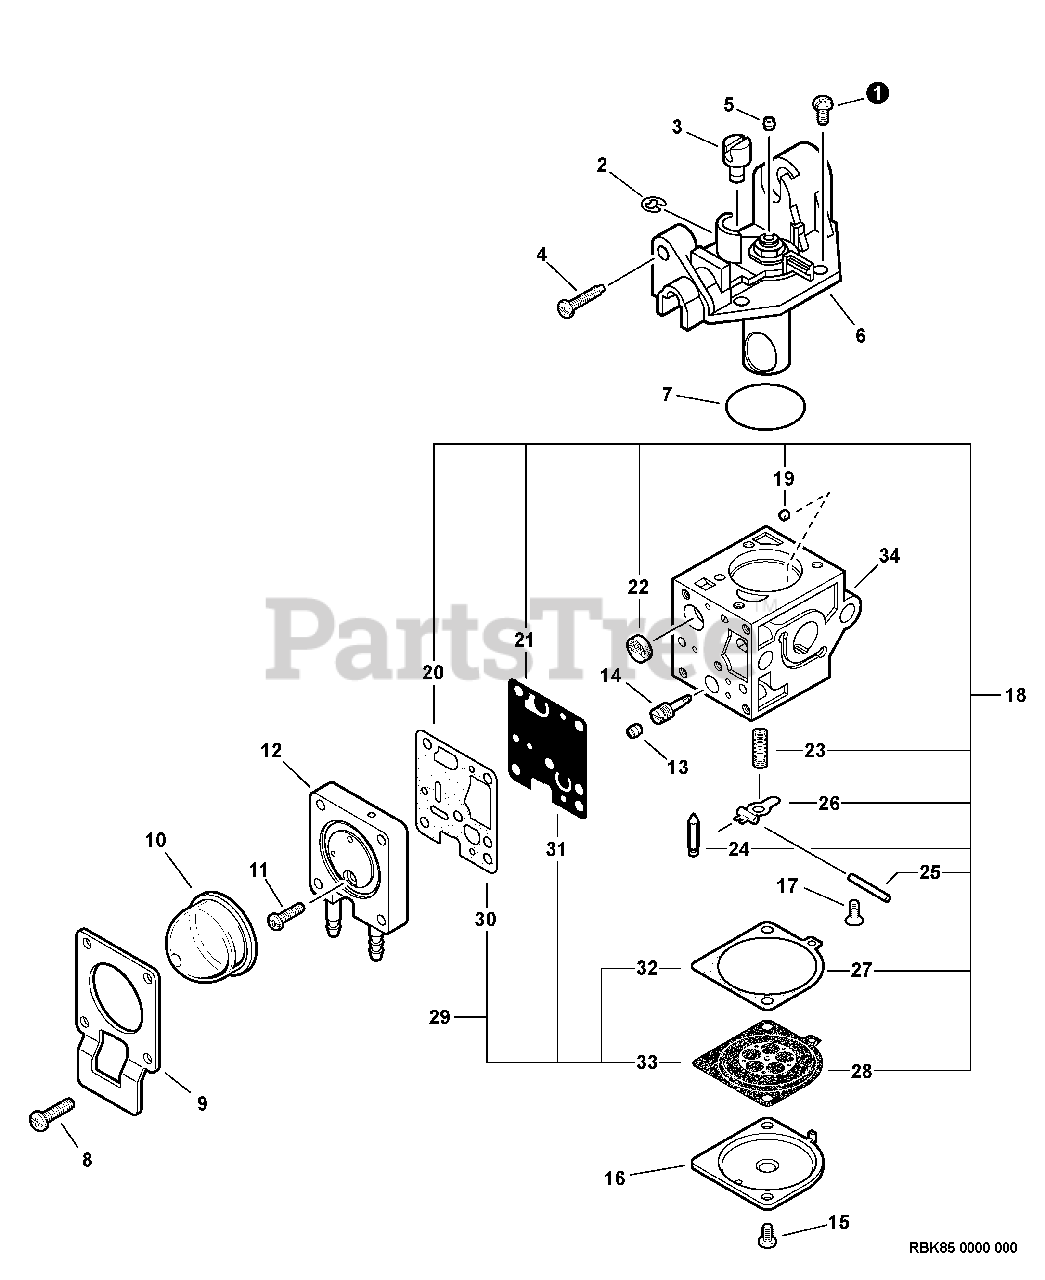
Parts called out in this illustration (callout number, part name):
4	SCREW, IDLE ADJUST
6	COVER ASSY, ROTOR
9	RETAINER, PURGE BULB
10	BULB, PURGE
12	BODY ASSY, PURGE
14	NEEDLE, HIGH SPEED
16	COVER, METERING DIAPHRAGM
18	REPAIR KIT
19	GUIDE, ROLLER
20	GASKET, PUMP
21	DIAPHRAGM, PUMP
22	STRAINER
23	SPRING, METERING LEVER
24	VALVE, INLET NEEDLE
25	PIN, METERING LEVER
26	LEVER, METERING
27	GASKET, DIAPHRAGM
28	DIAPHRAGM, METERING
29	GASKET / DIAPHRAGM KIT
30	GASKET, PUMP
31	DIAPHRAGM, PUMP
32	GASKET, DIAPHRAGM
33	DIAPHRAGM, METERING
34	BODY, CARBURETOR
